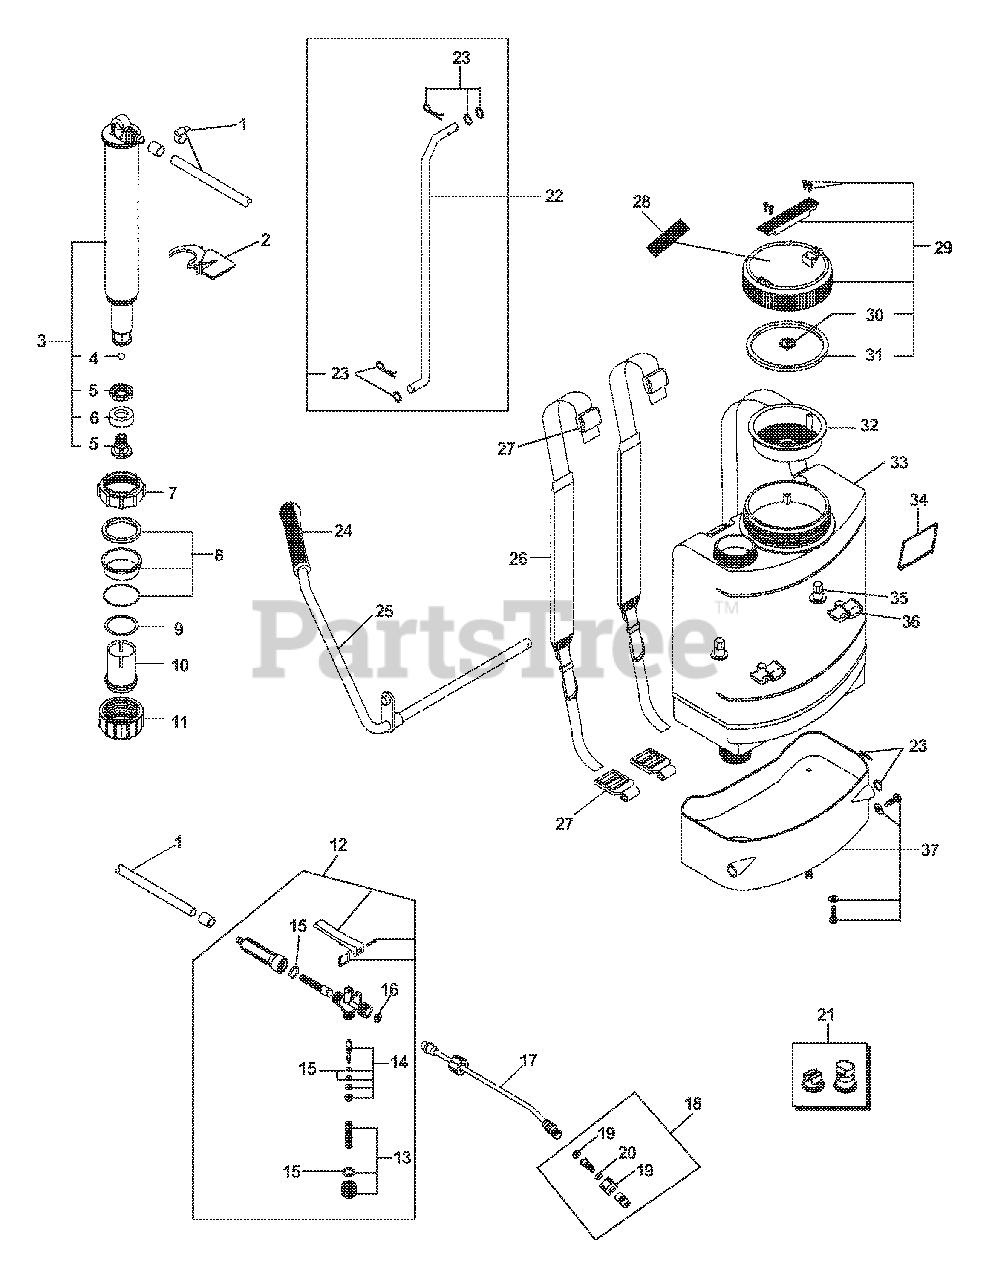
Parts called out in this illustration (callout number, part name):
2	AGITATOR
3	PUMP ASSY
4	BALL - PLASTIC
5	RING SEALING KIT
6	CUP, PISTON
7	CAP, PUMP
8	GUIDE, SEAL
9	O-RING
10	CYLINDER
11	CAP, BOTTOM
12	SPRAYER PISTOL ASSY
13	SEAL KIT
14	SPINDLE SET
15	O-RING KIT
16	WASHER
17	WAND - BRASS
17	WAND - PLASTIC
18	BRASS NOZZLE ASSY
19	NOZZLE HOLDER KIT
20	O-RING
21	SPRAY TIP SET
22	PUMP LEVER ASSY
23	PIN KIT
24	GRIP
25	PUMP, HANDLE
26	STRAP ASSY
28	LABEL - CAUTION
29	CAP ASSY
30	VALVE, CHECK
31	SEAL, CAP
32	STRAINER, DEBRIS
33	TANK
34	LABEL - CAUTION
35	NUT - PLASTIC
36	CLIP KIT
37	TANK BASE ASSY
